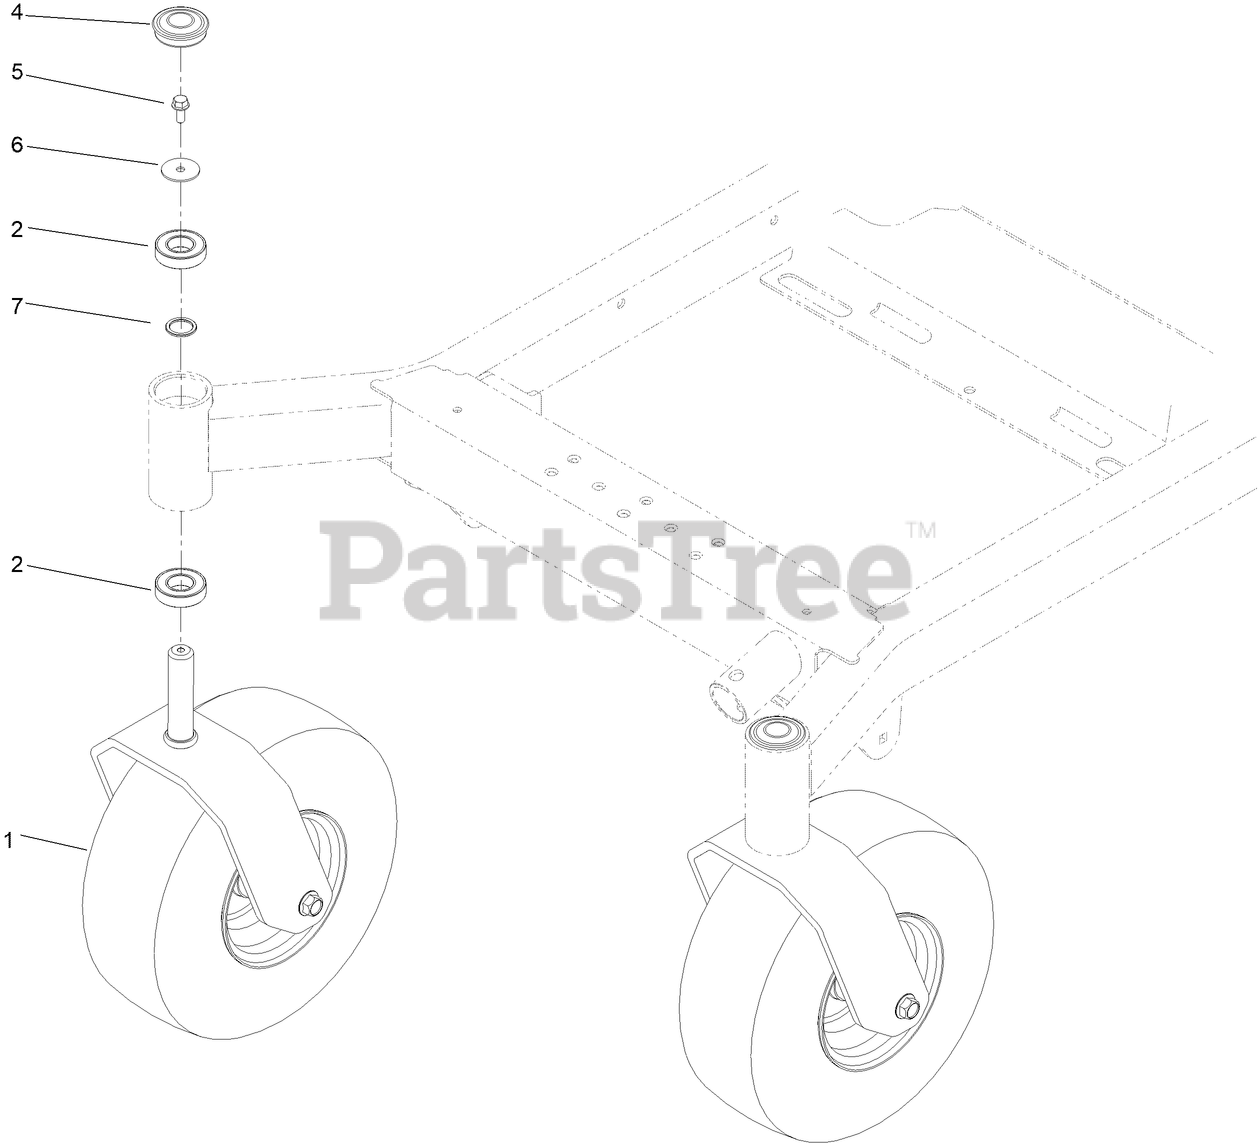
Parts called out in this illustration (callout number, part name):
1	ASM, FRONT CASTER W/ FORK
2	BEARING-BALL
4	CAP,GREASE
5	SCREW-HHF
6	WASHER-FLAT
7	SPACER-BEARING
